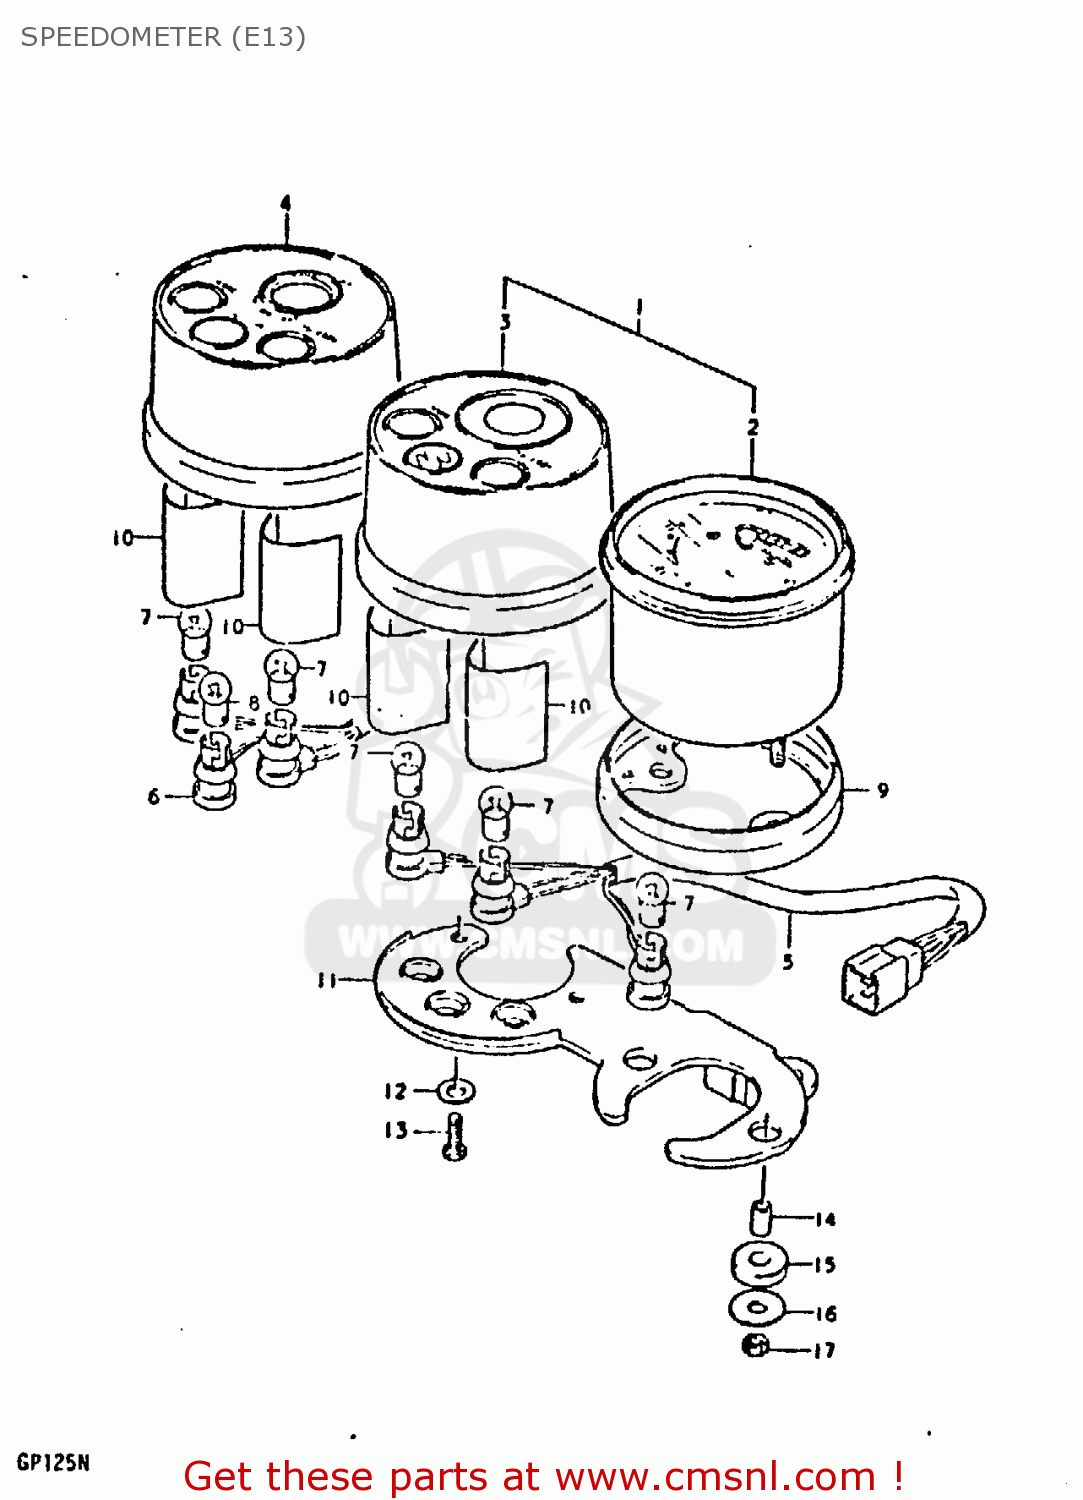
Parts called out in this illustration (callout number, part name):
1	SPEEDOMETER ASSY (KILO SCALE)
2	SPEEDOMETER
3	CASE
4	CASE,PILOT BULB
5	SOCKET
6	SOCKET
7	BULB(6V/3W)
8	BULB(6V1.7W,STANLEY,A61A)
9	CUSHION
10	REFLECTOR,PILOT LAMP
11	BRACKET
12	WASHER
13	BOLT
14	SPACER
15	CUSHION,SPEEDOMETER
16	WASHER (5.5X18X1.6)
17	NUT
